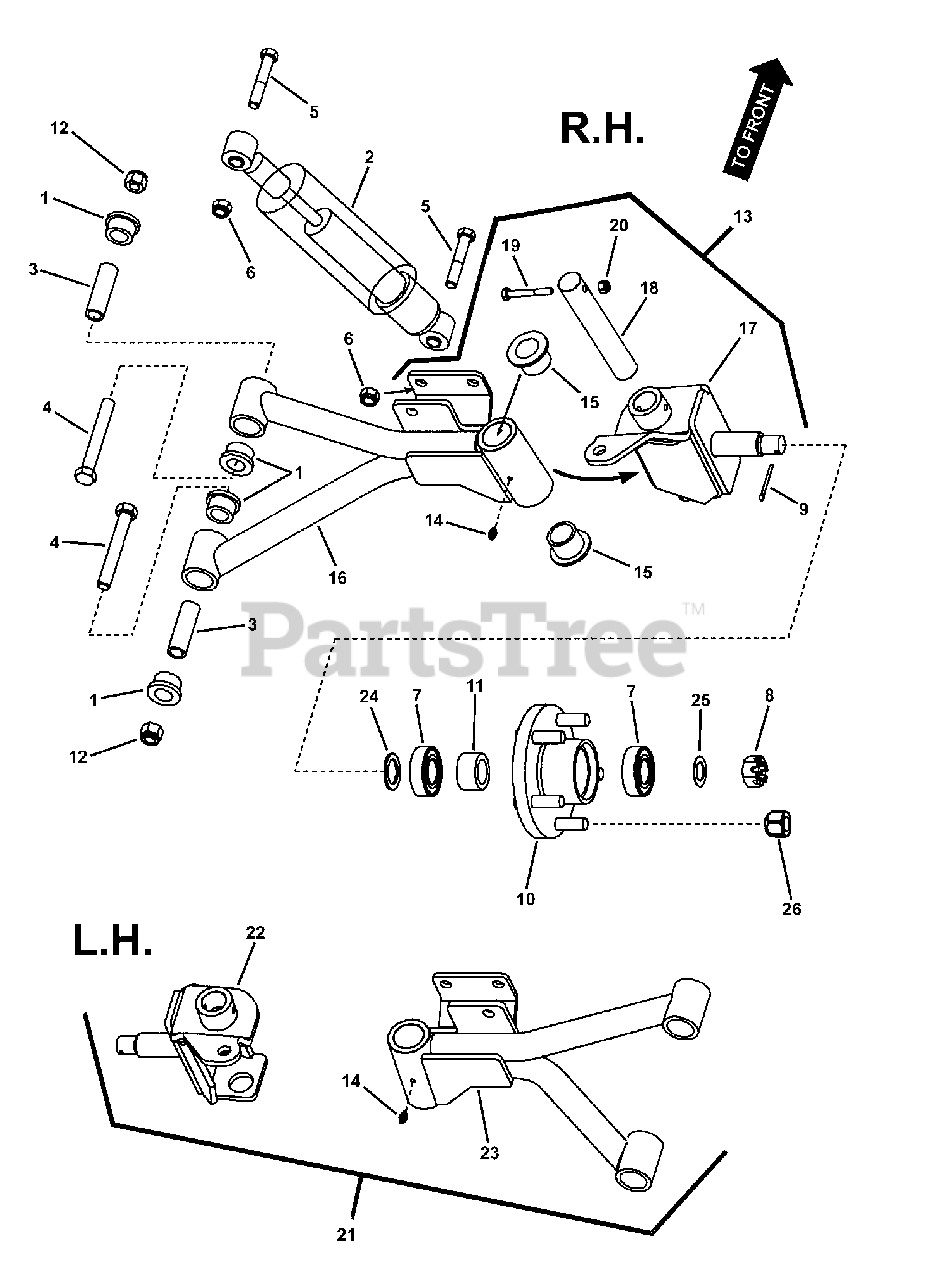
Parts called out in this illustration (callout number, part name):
1	BUSHING, Suspension
2	ASSEMBLY, Shock/Spring
3	SLEEVE, Suspension
4	BOLT, Hex Head, 1/2-13 x 3-3/4 GR 5
5	CAPSCREW, Hex Head, (Special) 7/16-20 x 2-1/2 GR 5
6	NUT, Hex Top Lock, 7/16-20
7	BALL BEARING, 6205-2RS
8	NUT, Slotted Hex, 3/4-16 GR 5
9	COTTER PIN, 1/8 x 1-1/2
10	WHEEL HUB, Front
11	SPACER, Front Wheel
12	NUT, Hex Nyloc, 1/2-13
13	A-ARM & SPINDLE ASSEMBLY, RH (Includes Ref. Nos. 14 thru 20)
14	FITTING, Lube 3/16 Serrated
15	BUSHING, Caster
16	A-ARM ASSEMBLY, RH
17	SPINDLE ASSEMBLY, RH
18	ROD, Spindle Pivot
19	CAPSCREW, Hex Head, G1/4-20 x 2 R 5
20	NUT, Hex Nyloc, 1/4-20
21	A-ARM & SPINDLE ASSEMBLY, LH (Includes Ref. Nos. 14, 15, 18, 19, 20, 22 & 23)
22	SPINDLE ASSEMBLY, LH
23	A-ARM ASSEMBLY, LH
24	BUSHING, 14 Gage Machine
25	THRUST WASHER, 3/4 I.D.
26	LUG NUT, 1/2-20 Hex
